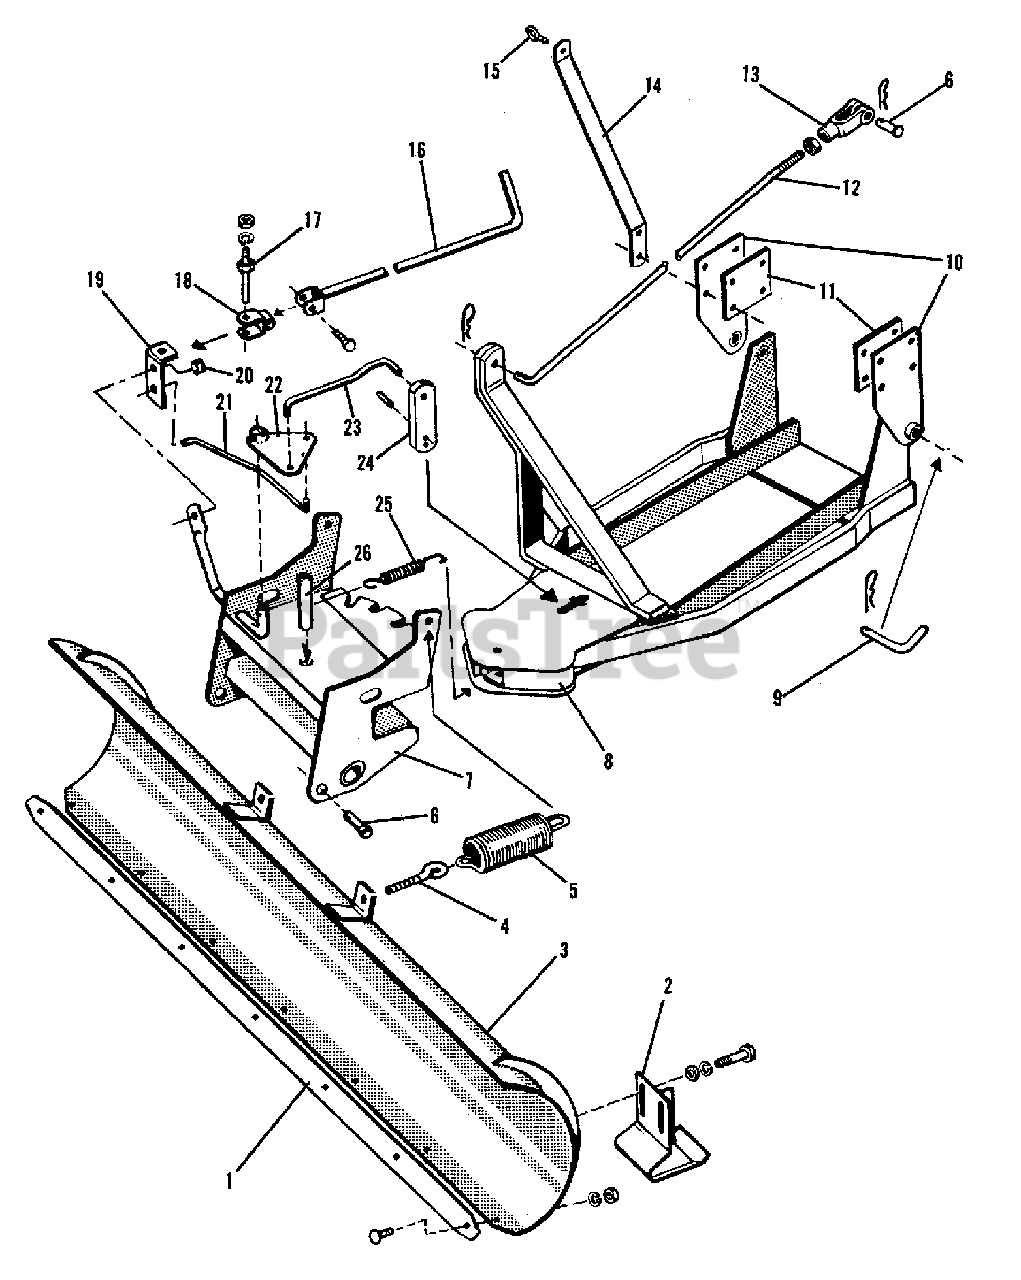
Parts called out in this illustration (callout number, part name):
1	PLATE, Wear
1	BOLT, 3/8NC x 1
1	LOCKWASHER, 3/8
1	NUT, 3/8NC
2	SHOE ASSEMBLY, Blade
2	CAPSCREW, 3/8NC x 3/4
2	LOCKWASHER, 3/8
2	WASHER, 3/8
3	BLADE ASSEMBLY, 46" Width
4	BOLT, Eye
4	NUT, 5/16NC
6	PIN, Yoke
6	PIN, Cotter, 1/8 x 1
7	FRAME ASSEMBY, Pivot
8	BAR ASSEMBLY, Push (Prior S/N 08502001)
8	BAR ASSEMBLY, Push (Effective S/N 08502001 & Up)
9	PIN, Hitch
9	PIN, Hair Clip
10	PLATE ASSEMBLY, L.H. Hitch
10	PLATE ASSEMBLY, R.H. Hitch
10	CAPSCREW, 3/8NC x 1
10	LOCKWASHER, 3/8
11	PLATE, Threaded Nut
12	ROD, Lift
12	NUT, Jam, 1/2NF
12	PIN, Hair Clip
13	YOKE, Lift Rod
14	BRACKET, Handle
15	BOLT, Eye
15	LOCKWASHER, 1/4
15	NUT, 1/4NC
16	HANDLY ASSEMBLY, Angle Adjustment
16	CAPSCREW, 5/15NC x 1-1/2
16	NUT, 5/16NC, Lock
17	STUD, Pivot
17	LOCKWASHER, 5/16
17	NUT, 5/16NC
17	PIN, Hair Clip
18	FORK ASSEMBLY, Handle Adjustment
19	ARM, Pivot
20	CAPSCREW, 5/16NC x 1
20	WASHER, 5/16, Plain
20	LOCKWASHER, 5/16
20	NUT, 5/16NC
21	ROD ASSEMBLY, Pivot
21	PIN, Cotter, 3/32 X 3/4
22	PLATE ASSEMBLY, Pivot
22	PIN, Cotter, 1/8 x 1
23	ROD, Latch
23	PIN, Cotter, 3/32 X 3/4
24	LATCH, Pivot
24	PIN, Roll, 7/32 x 1
25	SPRING, Latch
26	PIN, Pivot
26	PIN, Cotter, 3/16 x 1-1/4
